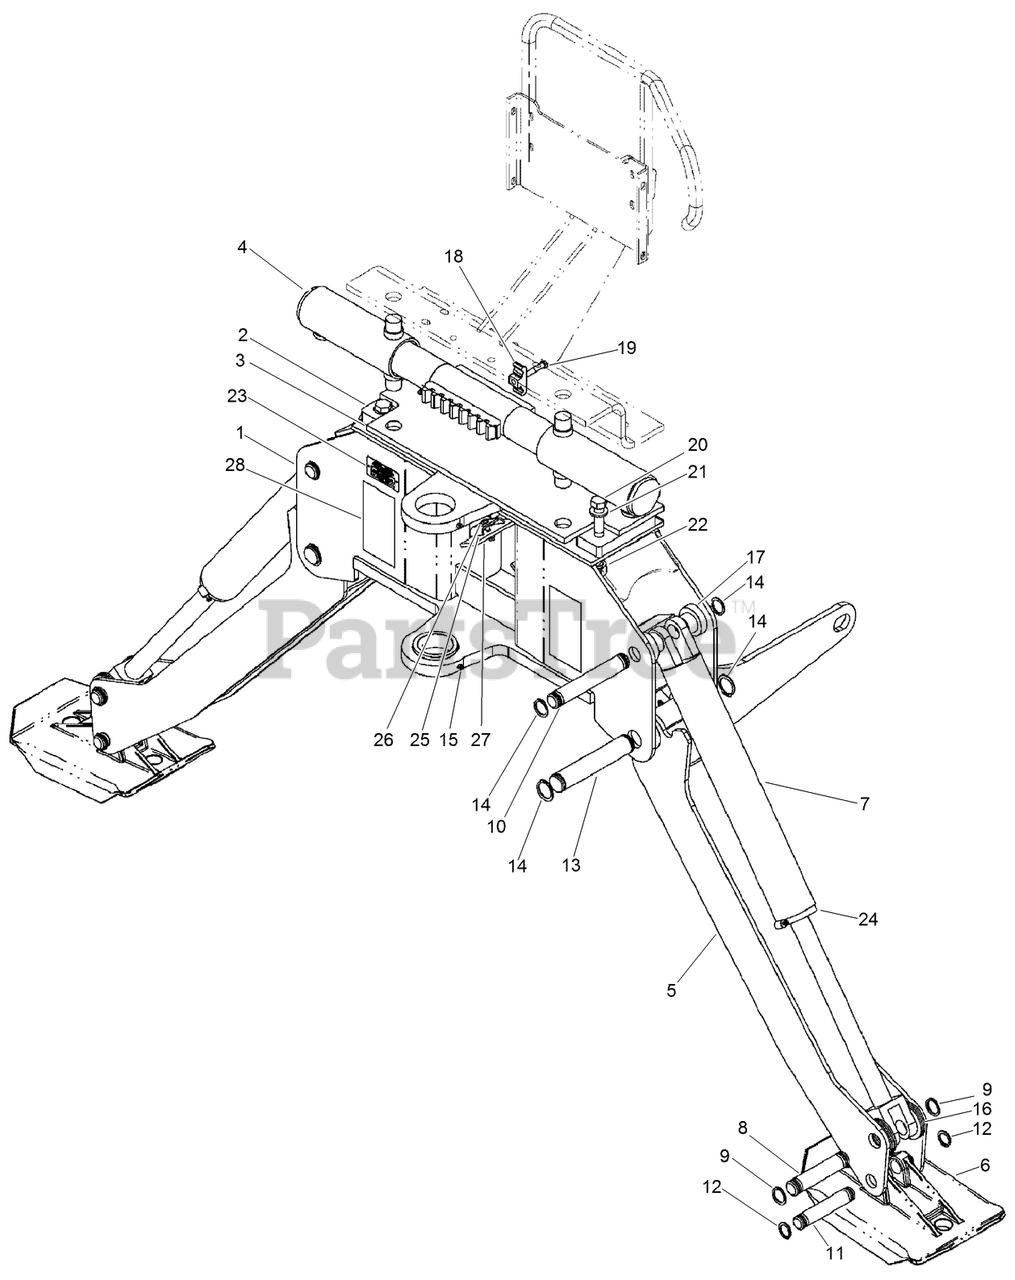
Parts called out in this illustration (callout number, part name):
1	WELDMENT-Frame, Bachhoe Mounting
2	ASM-Plate, Upper
3	PLATE-Mounting
4	CYLINDER-Hydraulic
5	WELDMENT-Stabilizer
6	PAD-Stabilizer Cast
7	HYD CYLINDER ASM
8	PIN-STABILIZER (CYLINDER ROD END)
9	RING-RETAINING
10	PIN-STABILIZER CYLINDER TO ARM
11	PIN (STABILIZER PAD END)
12	RING-RETAINING
13	PIN-Stabilizer Arm
15	FITTING-Lube 1/4-28 Tpr SAE-LT .54 Long
16	WASHER-FLAT (HARDENED)
17	BUSHING
18	CLAMP-Tube
19	BOLT-Hex Hd 3/8 x 2 GR5 ZND
21	WASHER-Flat
22	NUT-Prev Trq 3/4 GRC CAD Direct
23	PLATE - Serial Number
24	CLAMP-Hose #56
25	CLAMP-Tube, 7/8
26	BOLT-Hex, 5/16 NC x 1-1/2 inch
27	NUT-Prev Trq 5/16 GRA CAD NONDIR
28	DECAL-Danger, BH Crush Hazard
